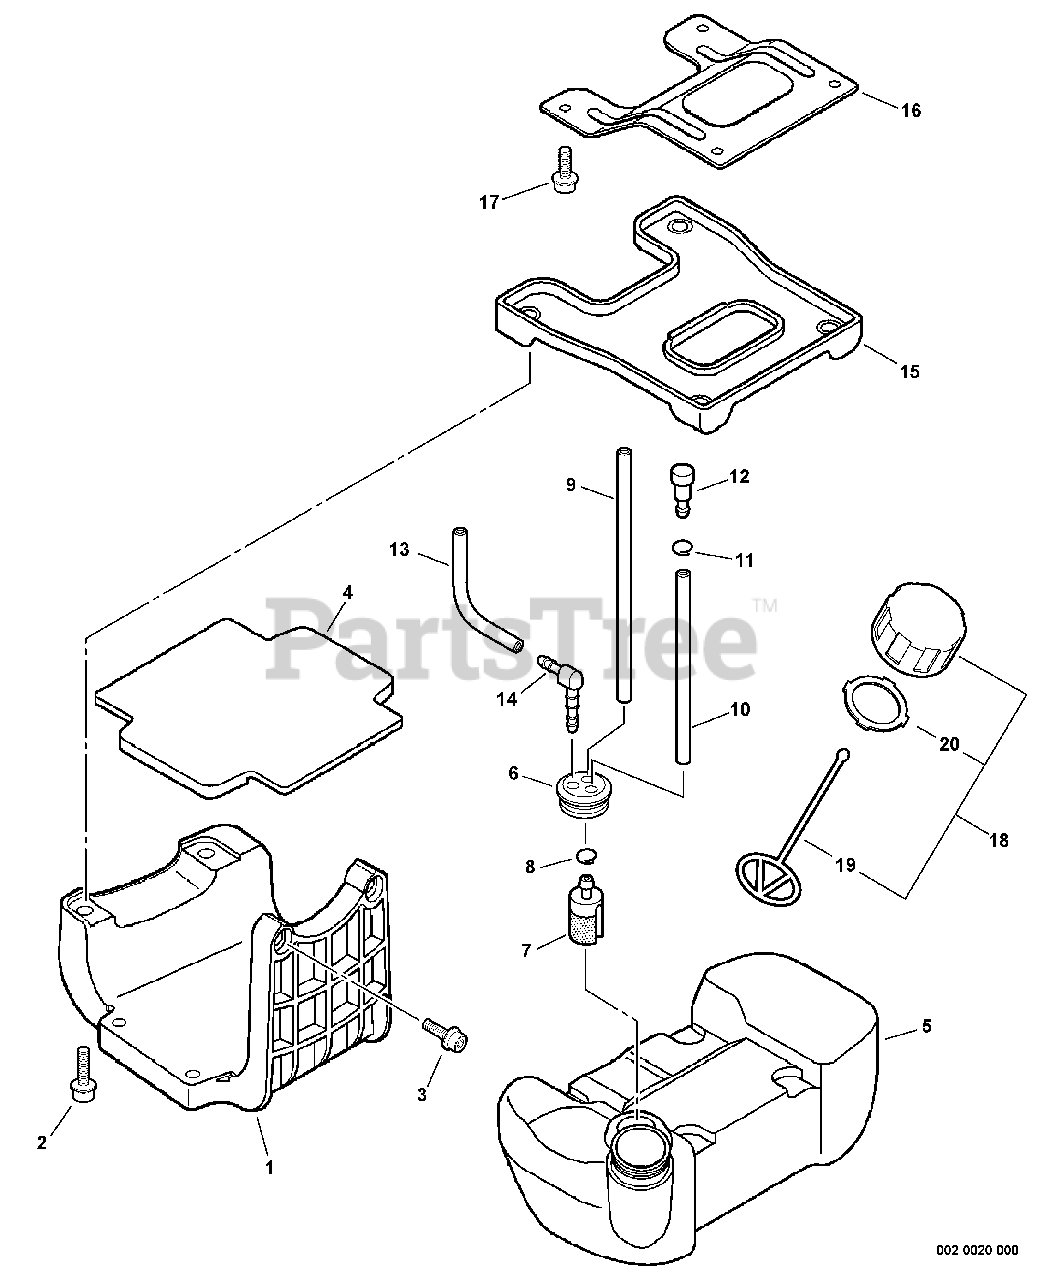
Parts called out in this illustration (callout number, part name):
1	GUARD, FUEL TANK
2	BOLT 5×20
3	BOLT 5×25
4	CUSHION, FUEL TANK
5	TANK, FUEL
6	GROMMET, FUEL
7	FILTER, FUEL
8	CLIP Ø6.5 MM
9	PIPE, FUEL 3×6×180 BLACK
10	PIPE, FUEL 3×6×120 BLACK
11	CLIP Ø6.5 MM
12	VENT ASSY
13	PIPE, FUEL 3×6×60 CLEAR
14	CONNECTOR, PIPE Ø5.4
15	CUSHION, UPPER
16	BRACKET, FUEL TANK
17	BOLT 5×12
18	CAP ASSY, FUEL
19	CONNECTOR, CAP L= 100 MM
20	GASKET, FUEL CAP
